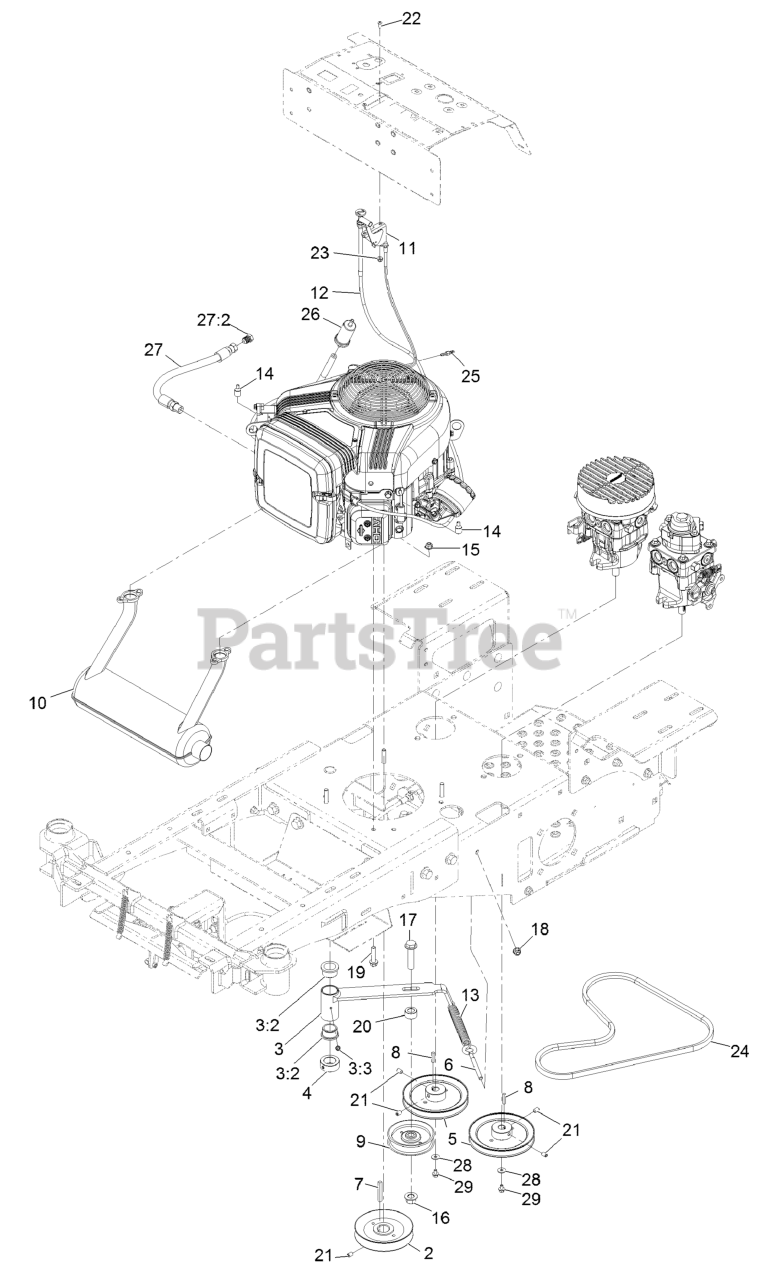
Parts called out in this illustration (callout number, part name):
2	PULLEY-DRIVE
3	ASM, ARM-TENSION
3:2	BUSHING-FLANGE
3:3	FITTING-GREASE, ZERK
5	HYDRO PULLEY SPRAYER
6	BOLT, EYE - 5/8 X 5/16-18 X 5
9	PULLEY-IDLER, FLAT
10	BRIGGS 16/18 HP MUFFLER
11	CABLE-THROTTLE
12	CABLE-CHOKE
13	SPRING-EXTENSION
14	Tube-Heat Shrink, 1/2
15	Nut-Hex Flange
16	Nut-Lock 1/2-13
17	Screw-HHF
18	NUT-HF, NI
19	5/16-18X 1-1/2 HEX FLANGE
21	Setscrew-HSH
22	Screw-HSBH
23	Nut-Hex Flange
24	A-48 JR-36 DRIVE BELT
25	Fitting-STR
26	FILTER-FUEL
27	ASM, Oil Drain Hose W/Plug
29	SCREW-HHF
